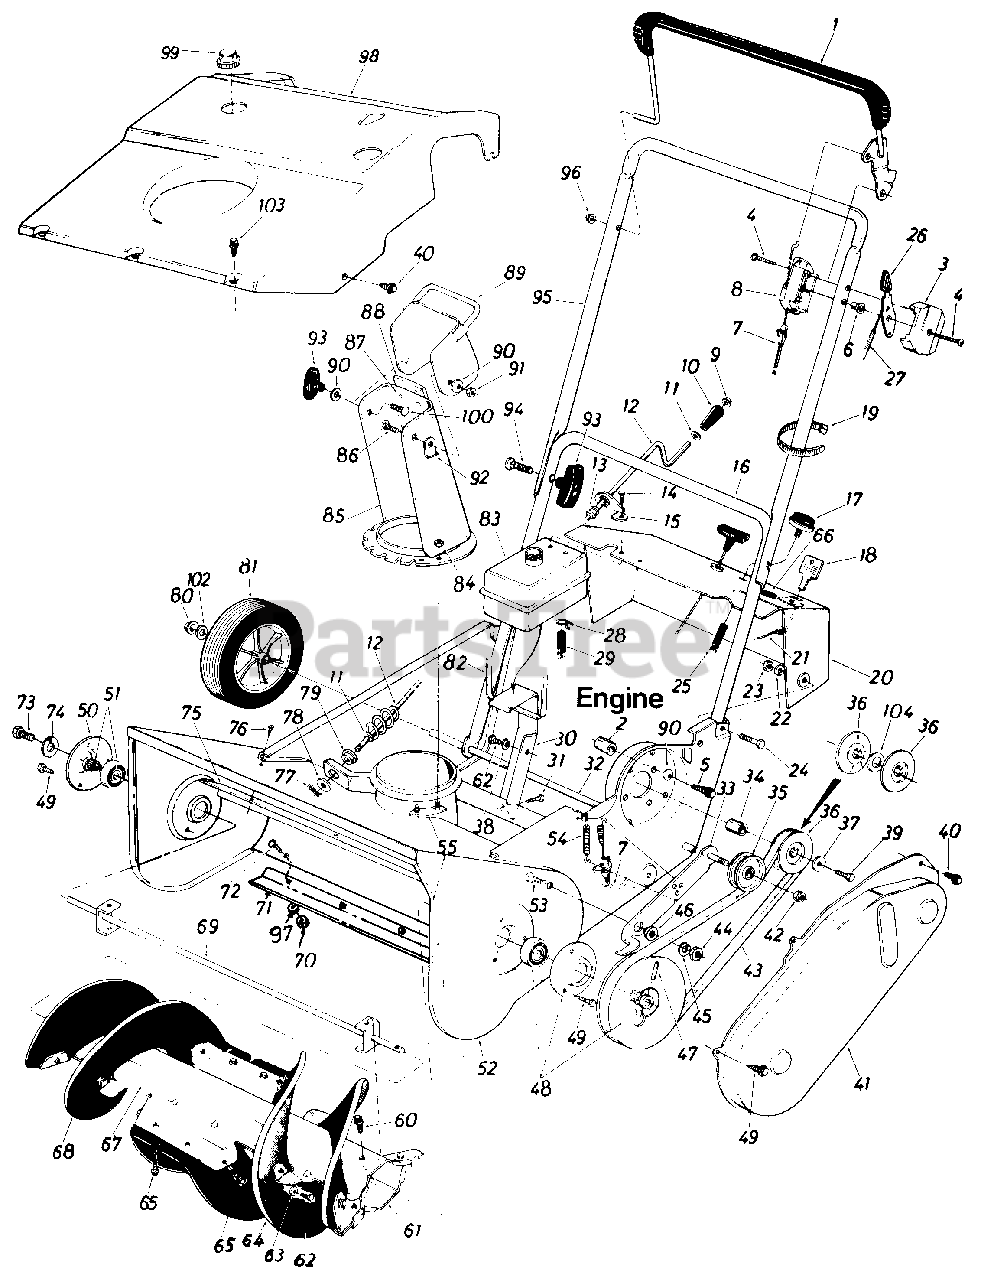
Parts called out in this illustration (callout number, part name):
1	Clutch Control Handle Ass'y.
2	Spacer.325" I.D. x .625" O.D. x.87" Lg.
3	Control Panel Half
4	Truss Mach. Hi-B Tap Scr. #12 x 1.50" Lg.
5	Hex Bolt 5/16-18 x 1.50" Lg.
6	Control Disc Pin
7	Clutch Cable 35" Lg. Black
8	Clutch Panel Half
9	Push Nut 3/8" Rod
10	Knob Black 3/8" Dia. Hole
11	Fl-Wash. .385" I.D. x .62" O.D.
12	Chute Crank Ass'y.
13	Chute Crank Grommet
14	Hex Tap Scr. 1/4" x .75" Lg.
15	Upper Chute Crank Brkt.
16	Lower Handle
17	Primer
18	Starter Key
19	Cable Tie
20	Dash Panel Ass'y.
21	Ignition Wire
22	L-Wash. 5/16" I.D.
23	Hex Nut 5/16-18 Thd.
24	Hex Bolt 5/16-18 x 1.50" Lg.
25	Primer Hose 1/8" I.D. x 11 "
26	Throttle Lever
27	Throttle Wire
28	Hose Clamp .406" Dia.
29	Gas Line 9" Lg.
32	Wheel Axle
33	Idler Brake Brkt. Ass'y.
34	Spacer
35	Fl-Idler 2.00" x 1" w/Flange
36	3/8" V-Pulley .625" I.D. x 2.25
37	Bell-Wash. .345" I.D. x .88"
38	L-Wash. 1/4" I.D.
39	Hex Scr. 5/16-24 x .75" Lg.
40	Hex L-Wash. Hd. AB-Tap Scr. 1/4 x.62"
42	Hex L-Nut 3/8-24 Thd.
43	V-Belt 1/2" x 34" Lg.
44	Hex Nut 5/16-18 Thd.
45	L-Wash. 5/16" I.D.
46	Shld. Spacer 1.0" O.D. x .315 I.D.
47	Spring Pin Spir. 114" Dia. x 1.00" Lg.
48	Kit-Bearing, Cup and Pulley
49	Hex "B"-Tap Scr. 1/4-20 x .38" Lg.
52	Blower Housing Ass'y.
53	Truss. Mach. Scr. 5/16-18 x .75" Lg.
54	Extension Spring .33" O.D. x 1.12" Lg.
55	Chute Flange Keeper Ass'y.
60	Hex L-Wash. Hd. AB-Tap Scr. 114 x .62" Ly.
61	Auger Half 21.0" Lg.
62	Hex Wash. Hd. Self-Tap Scr. 1/4-20 x .50" Lg.
63	Fl-Wash. .28" I.D. x .74" O.D.
64	8.5" Dia. Rubber Spiral
65	Hex B-Tap Scr. 1/4 x .62" Lg.
66	Plastic Plug
67	Auger Half 21.0" Lg.
68	8.5" Dia. Rubber Spiral
69	Auger Axle Ass'y.
70	Hex Nut 1/4-20 Thd.
71	Shave Plate
72	Carriage Bolt 1/4-20 x .62"
73	Hex Wash. TT-Tap Scr. 1/4-20 x.75" Lg.
74	L-Wash. 1/4" I.D.
75	Thrower Housing Angle
76	Hex "B"-Tap Scr. 114" x .38" Lg.
77	Cotter Pin 3/32" Dia. x .75"
78	Fl-Wash. .385" I.D. x 1.5" O.D.
79	Hex Bushing .385" I.D.
80	Cap Speed Nut 1/2" Rod
81	Wheel Ass'y. 6 x 1.50
82	Cable Tie x 17.75" Lg.
83	Gas Tank
84	Hex Nylon L-Nut 1/4-20 Thd.
85	5.0" Dia. Chute Ass'y.
86	Carriage Bolt 5/16-18 x .62"
87	Rivet .250" x.44" Lg.
88	Chute Seal
89	Top Ghute Ass'y.
90	Bell-Wash. .345" I.D. x .88"
91	Hex Cent. L-Nut 5/16-18 Thd.
92	Top Chute Stop
93	Knob-Handle Ass'y.
94	Curved Hd. Carriage Bolt 5/16-18 x 1.75" Lg.
95	Upper Handle
96	Cap Speed Nut 5/16" Rod
97	Bell-Wash. .265" I.D. x .75" O.D.
98	Shroud
99	Gas Tank Cap
100	Carriage Bolt 5/16-18 x 1.00"
102	Fl-Wash. .75" O.D. x .50" I.D.
103	Hex AB-Tap Scr. #10 x .50"
104	Fl-Wash. .635" I.D. x .93" O.D.
